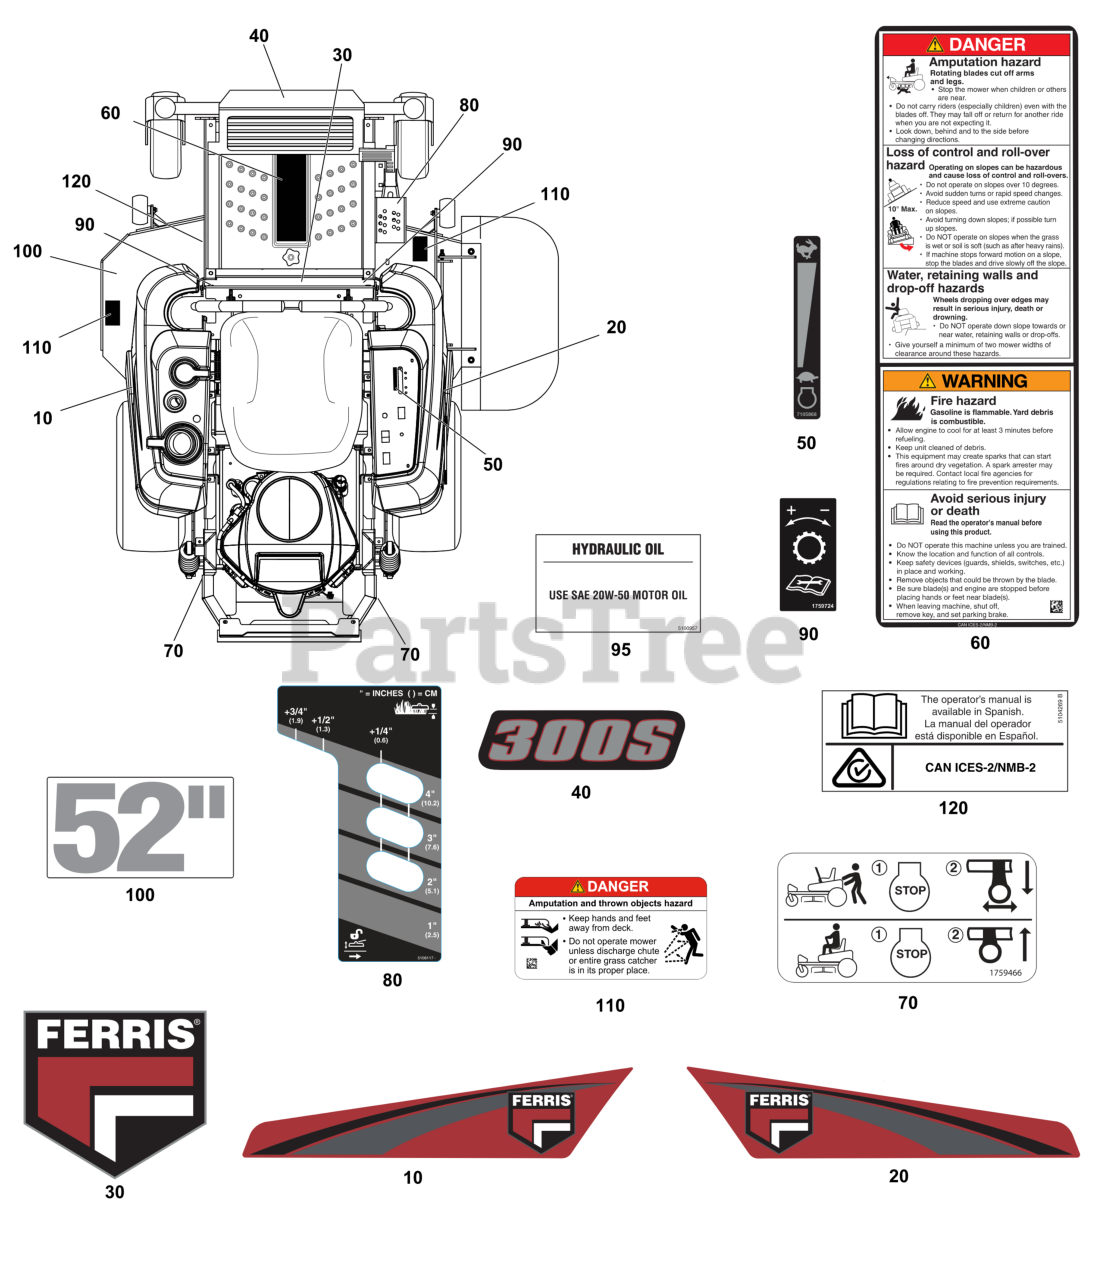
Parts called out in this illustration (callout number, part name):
10	DECAL, BRAND
20	DECAL, BRAND
30	DECAL, BRAND
40	DECAL, Model
50	DECAL, ENGINE SPEED
60	DECAL, Main Safety
80	DECAL, CUTTING HEIGHT
90	DECAL, Tracking Adjustment - ZT
95	DECAL
100	DECAL, 52
110	DECAL, Danger
